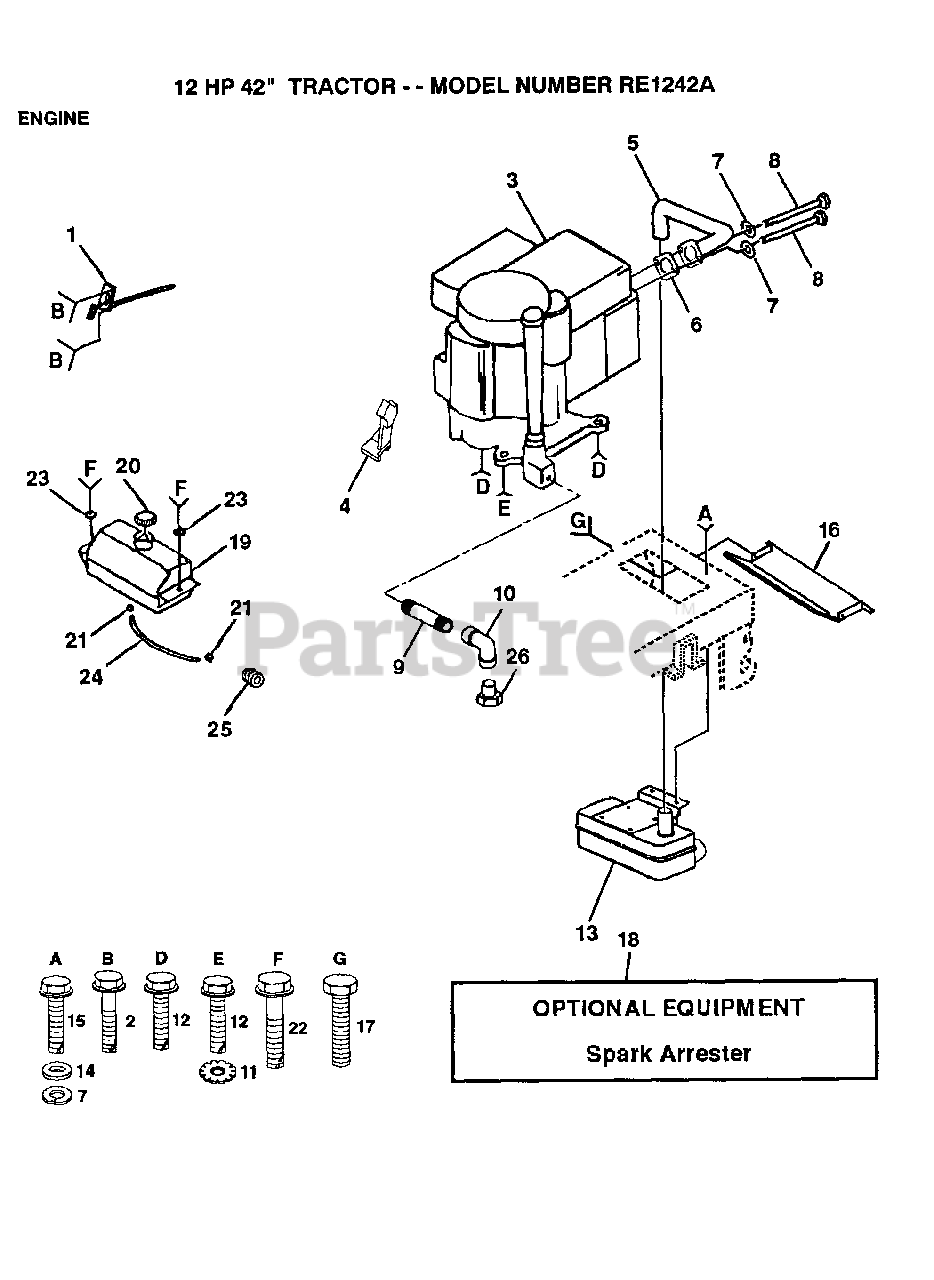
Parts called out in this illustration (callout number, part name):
2	SCREW LT
5	PIPE EXHAUST
7	LOCKWASHER
8	SCREW LT
9	PIPE NIPPLE
10	ELBOW
11	LOCKWASHER
12	SCREW
13	MUFFLER EUROPE
14	WASHER
15	SCREW
16	HEAT SHIELD
17	SCREW
18	SPARK ARREST KIT
19	TANK.FUEL.LT.
21	HOSE CLAMP
22	SCREW HEX CRT
23	WASHER
24	FUEL LINE T
